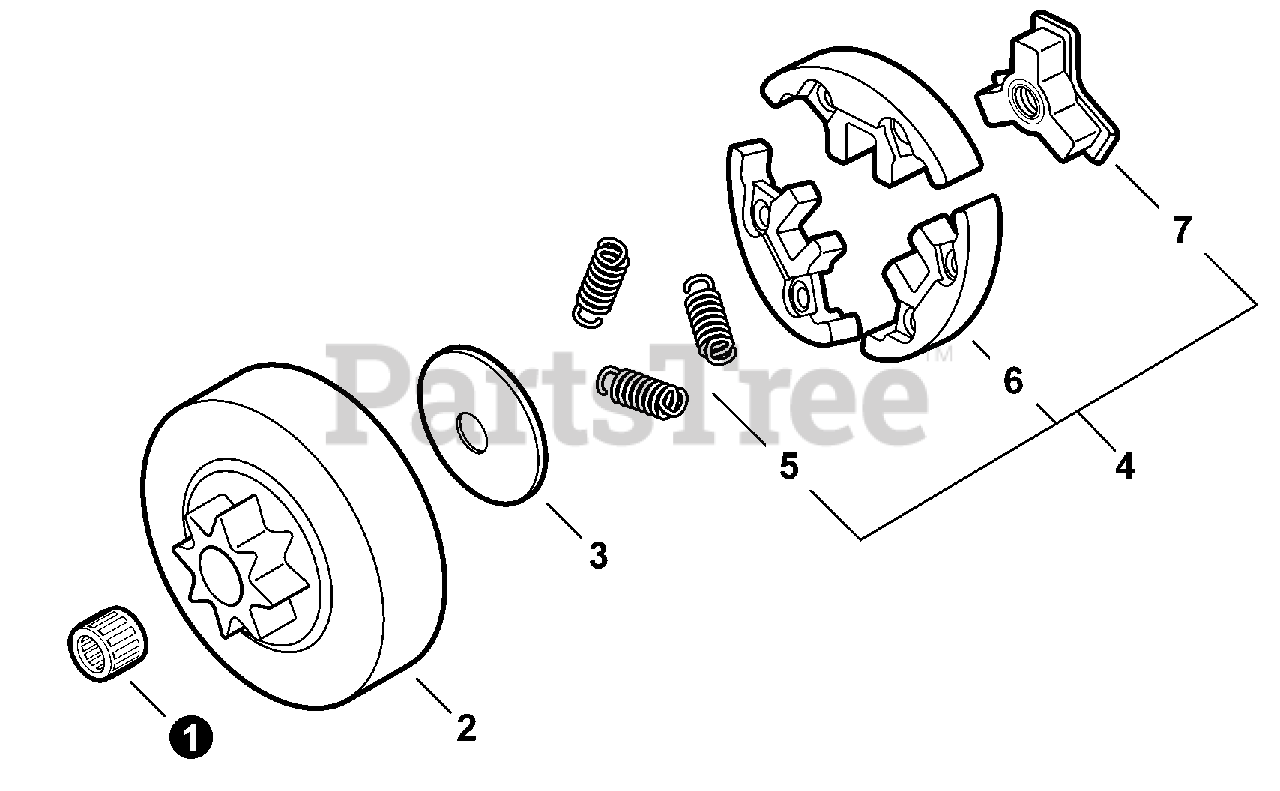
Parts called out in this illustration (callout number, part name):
1	BEARING, NEEDLE 10
2	DRUM, CLUTCH 3/8"
3	PLATE, CLUTCH
4	CLUTCH ASSY
5	SPRING, CLUTCH
6	SHOE SET, CLUTCH (3PCS)
7	HUB, CLUTCH
